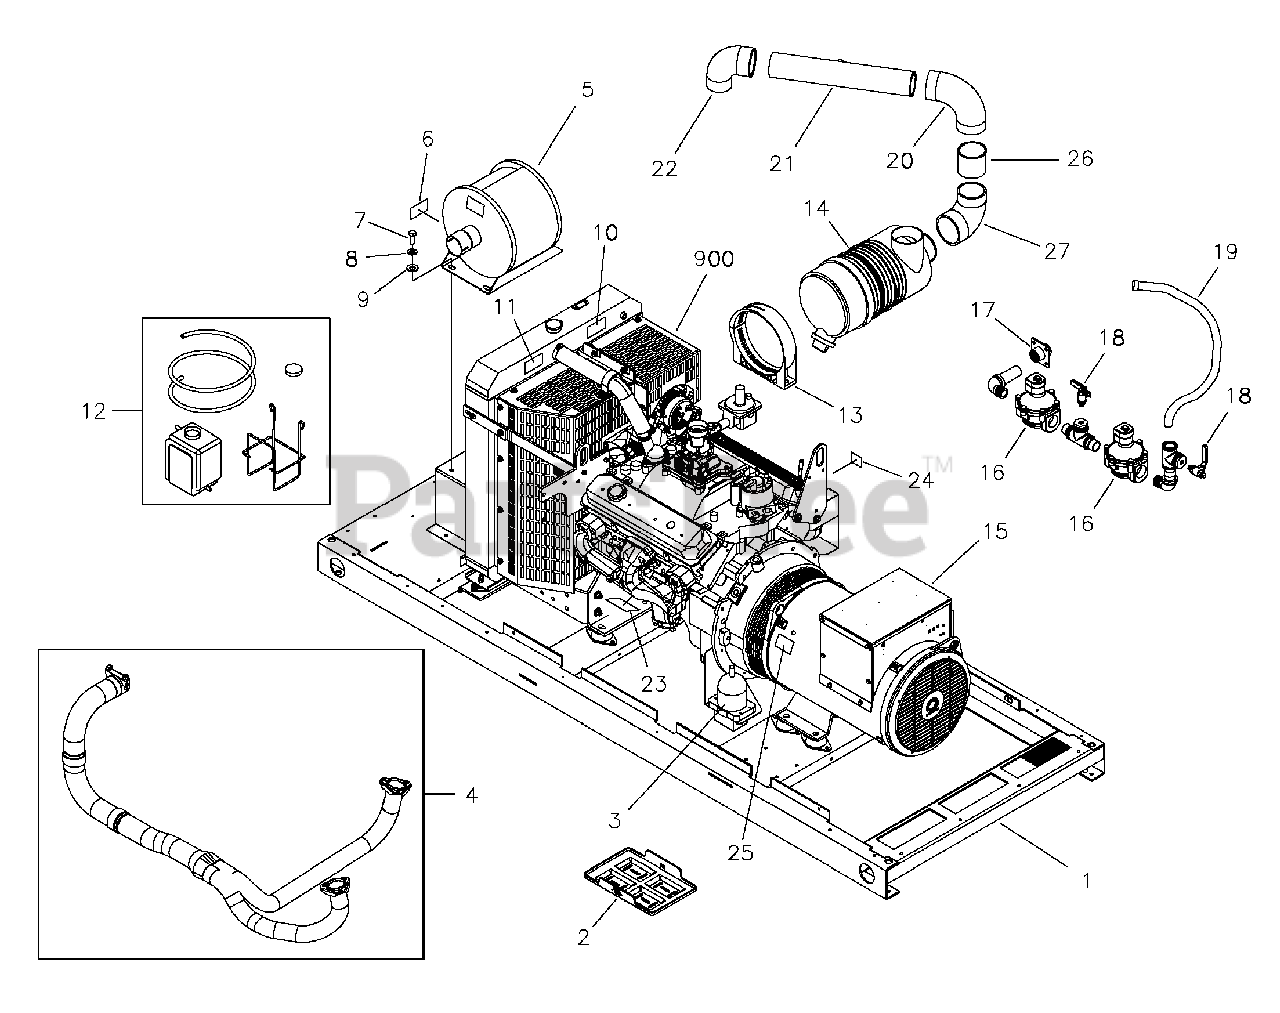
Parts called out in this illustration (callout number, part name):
3	ASSY, Heater, Tank
5	SILENCER, Muffler
6	DECAL, Burn Hazard
7	HHCS, 5/16 - 18 x 1
8	WASHER, 5/16 - M8, Lock
9	WASHER, 5/16 - M8, Flat
10	DECAL, Warning Hot Coolant
11	DECAL, Warning Moving Parts
12	KIT, Bottle Overflow
13	CLAMP, Air Cleaner
14	ASSY, Air Cleaner
15	ASSY, Alternator
16	ASSY, Fuel Valve
17	COUPLER, Fuel System
18	VALVE, Ball 1/4"
19	ASSY, Hose, Fuel
21	TUBE, Inlet, Air
23	DECAL, Warning, Hot
24	DECAL, Oil Drain
25	DECAL, Explosion Hazard
26	TUBE, Inlet, Air
900	ENGINE
